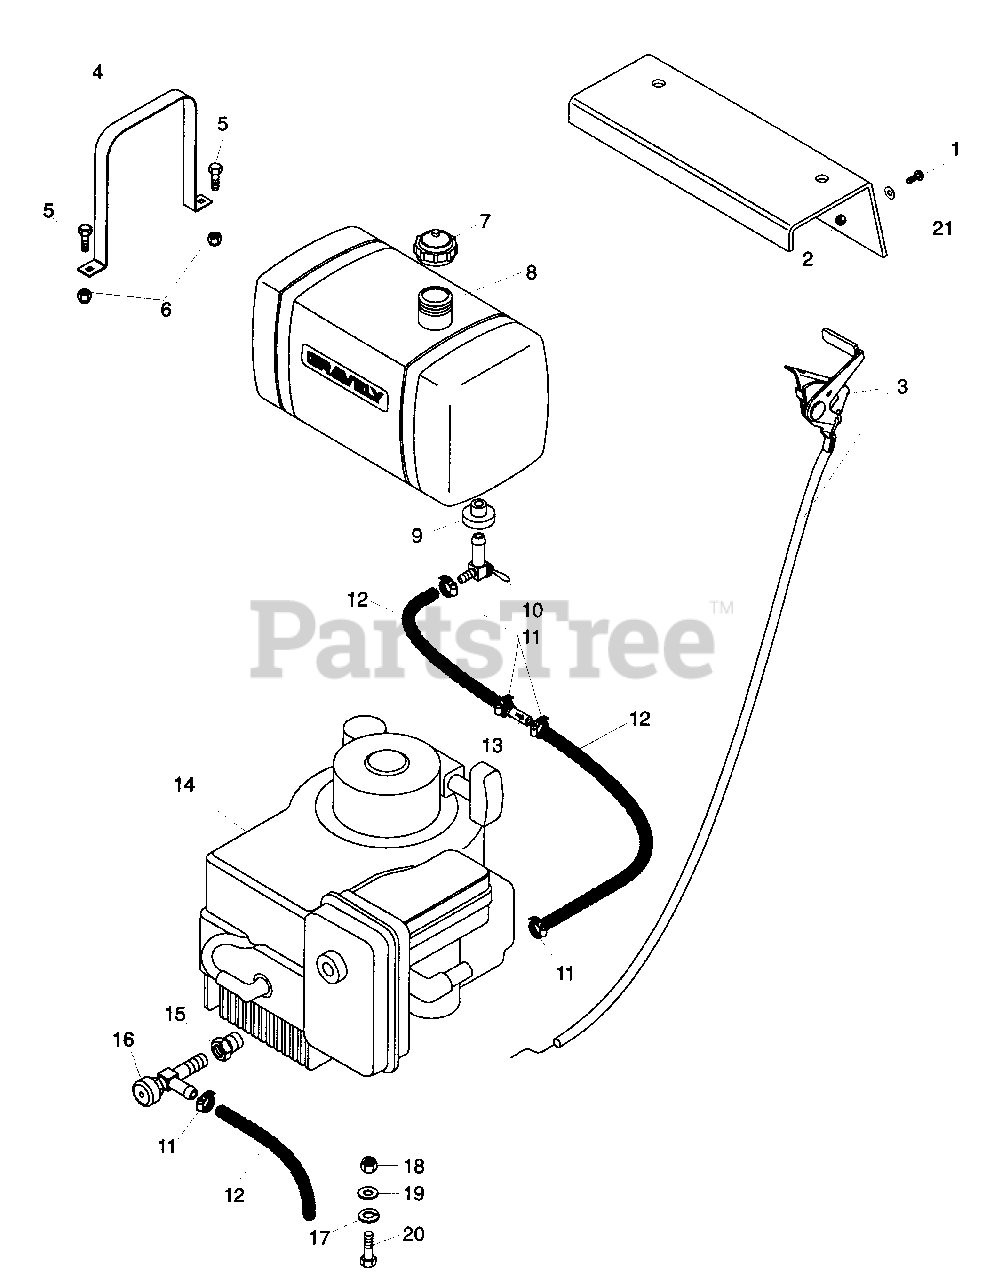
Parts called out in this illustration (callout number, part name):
1	Screw-Machine, Pan Head 6-32 x .75
2	Nut-Locking-Nylon 6-32 w/Insert
3	Assembly, Throttle Control/Cable
4	Tank Strap for 4.5 G Fuel Tank
5	Bolt-Hex .25-20 x .75 Grade 5
6	Nut-Locking-Center .25-20
7	Cap, Fuel Tank
8	Fuel Tank, 4.5 Gallon
9	Bushing, Flange .375 x 1.06 x .625
10	Valve, Ball Shut-Off
11	Hose Clamp
12	Gas Line-Bulk
13	Filter, Fuel
14	Engine, Kawasaki 12.5
14	Engine-14 HP Kawasaki
14	Engine, 12.5 HP Command
14	Engine, 15 HP Kohler Command
15	Adapter, Oil Drain
16	Cock, Oil Drain
17	Washer-Lock .313 x .078
18	Nut-Locking-Center .31-18
19	Washer-Flat-Steel .344 x .688 x .065
20	Bolt-Hex M8 x 1.25 x 30 Grade 5
21	Washer-Flat-Steel .194 X .492 X .047
